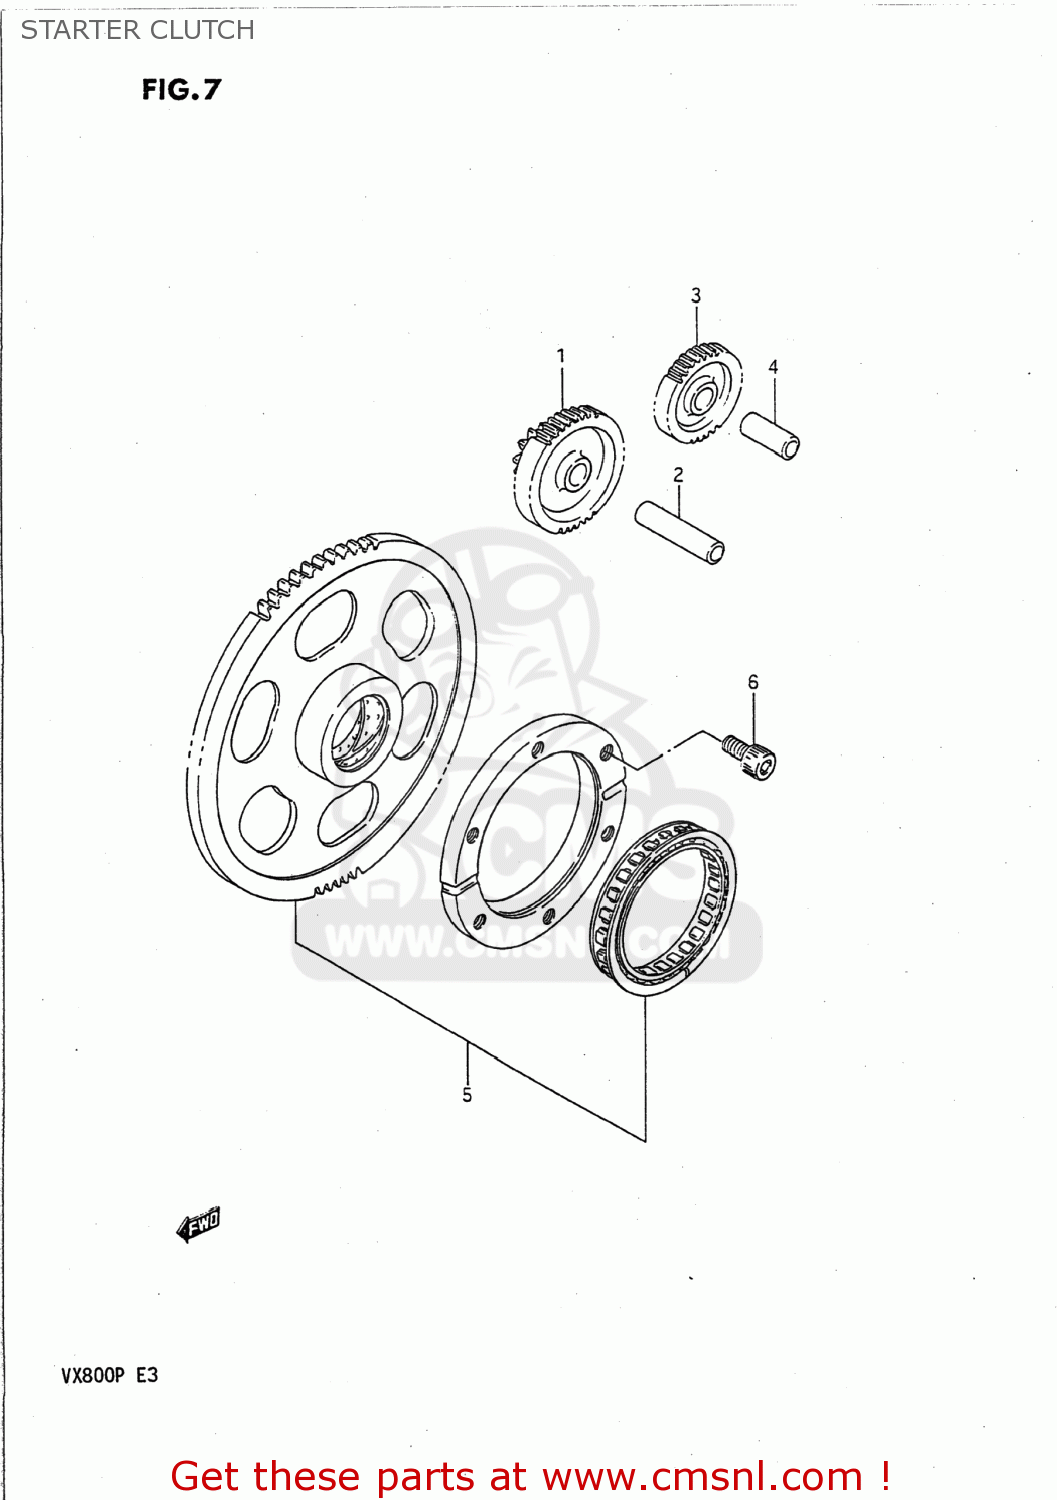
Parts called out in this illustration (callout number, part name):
1	GEAR,STARTER IDLE NO.1
2	PIN
3	GEAR,STARTER IDLE NO.2
4	PIN
5	CLUTCH SET,STARTER
6	BOLT
